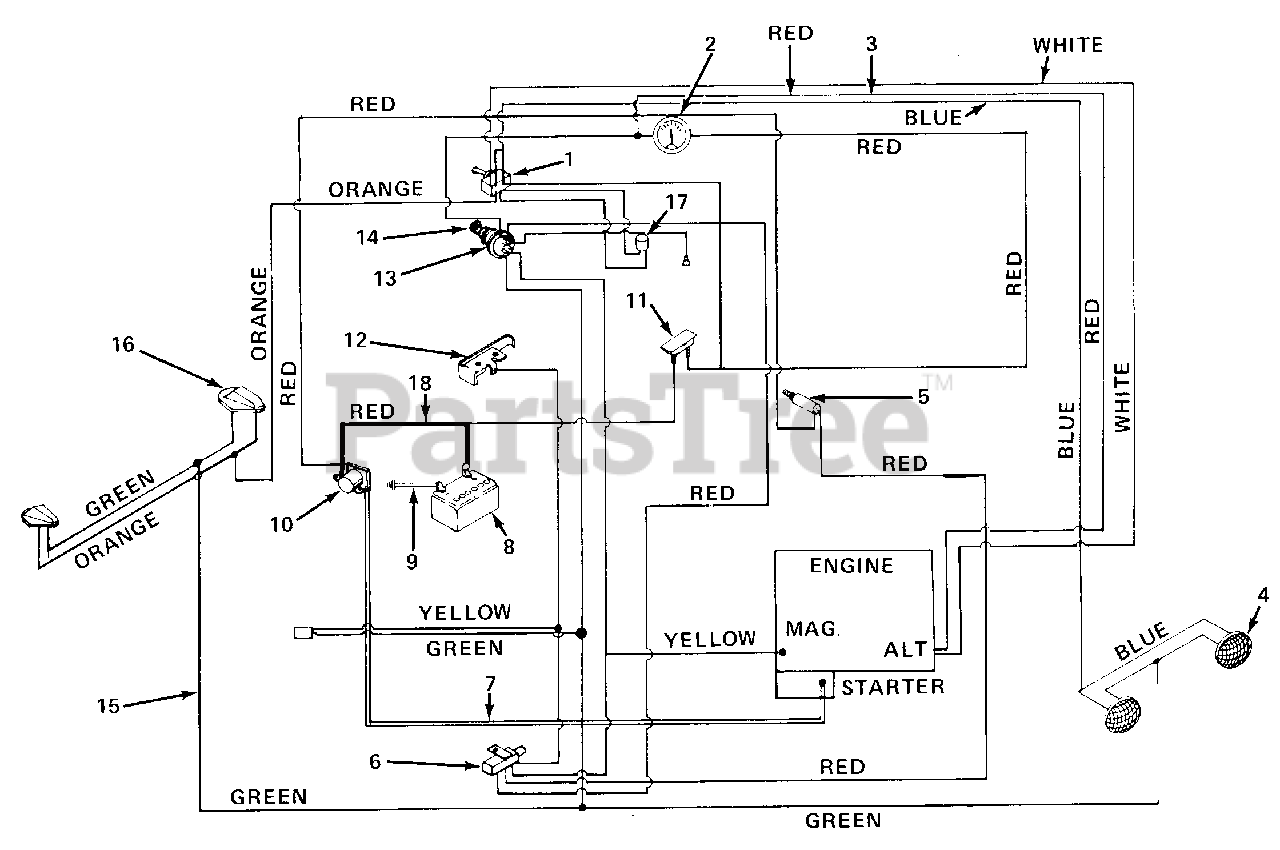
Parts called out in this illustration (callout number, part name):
1	Light Switch
2	Ammeter
3	Wire Harness
4	Head I ight
5	Safety Switch Ciutch
6	Safety Switch-P.T.O.
7	EIectric Wire
8	Battery 12 V
9	Electric Wire
10	Solenoid
11	Circuit Breaker
12	Spring Switch
13	Ignition Switch
14	Ignition Key
15	Tail Light Lead
16	Tail Light
18	Electric Wire
